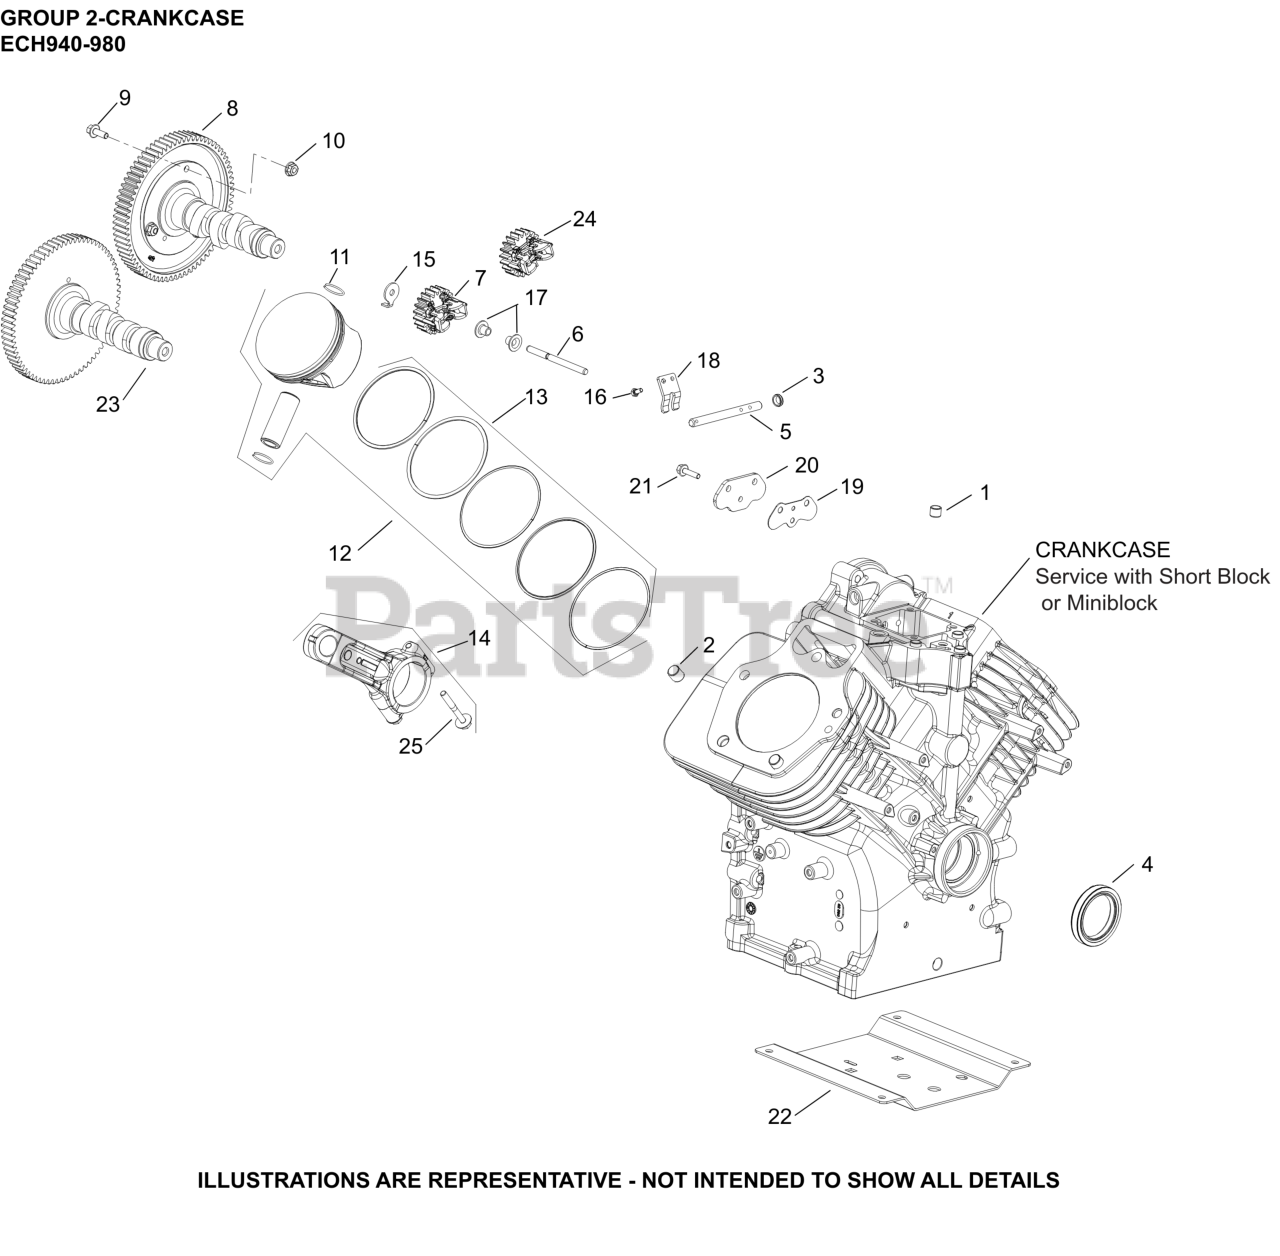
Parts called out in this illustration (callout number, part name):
2	PIN, LOCATING
3	SEAL, GOVERNOR CROSS SHAFT
4	SEAL, OIL FW SIDE, BLACK
5	SHAFT, GOVERNOR CROSS
6	SHAFT, GOVERNOR GEAR
10	NUT, FLG M6X1.0
11	RETAINER, PISTON PIN
12	RING, SET PISTON (STD)
13	KIT, PISTON (STD)
13	KIT, PISTON (0.25 OS)
13	KIT, PISTON (0.50 OS)
14	CONNECTING ROD ASSEMBLY
15	TAB, LOCKING
16	SCREW, HEX HEAD
17	PIN, GOVERNOR REGULATING
18	YOKE, GOVERNOR
19	GASKET, LIFTER FEED COVER
20	KIT, COVER, LIFTER FEED
21	SCREW, HEAVY HEX FLANGE
23	KIT, CAMSHAFT
24	KIT, GOVERNOR GEAR
25	KIT, ROD BOLTS
